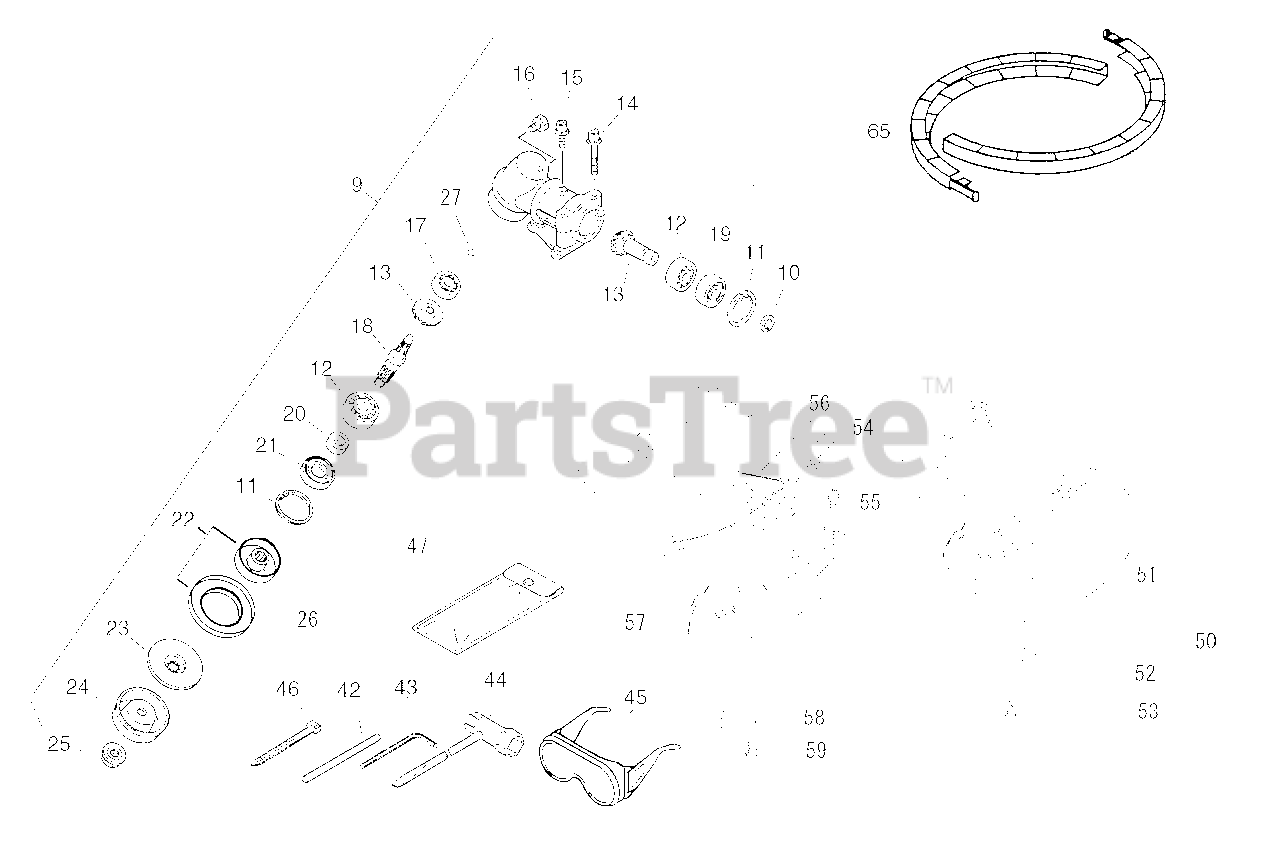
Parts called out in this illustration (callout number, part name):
9	GEAR CASE ASSY
10	RING, RETAINING 15
11	RING, SNAP 35
12	BEARING, BALL 6202
13	GEAR SET
15	BOLT 5×12
16	BOLT M8×8
17	BEARING, BALL 6001
18	SHAFT, GEAR
19	BEARING, BALL 6202
21	SEAL, OIL
22	PLATE, ADAPTOR
23	PLATE, ADAPTOR
25	NUT, LOCK
26	PLATE, ADAPTOR - LOWER
27	RING, RETAINING - 12
42	TOOL, LOCKING 5×120 MM
43	WRENCH, ALLEN 4 MM
44	T-WRENCH 17x-19 L200
45	GLASSES, SAFETY
46	STRAP, TIE
47	BAG, TOOL
50	SHIELD KIT
51	SHIELD, DEBRIS
53	SCREW, TAPPING 5×12
54	NUT M5
55	SCREW 5×18
56	BRACKET ASSY, SHIELD
57	SHIELD, BLADE
58	PLATE, SHIELD
59	BOLT 5×25
65	SCABBARD
